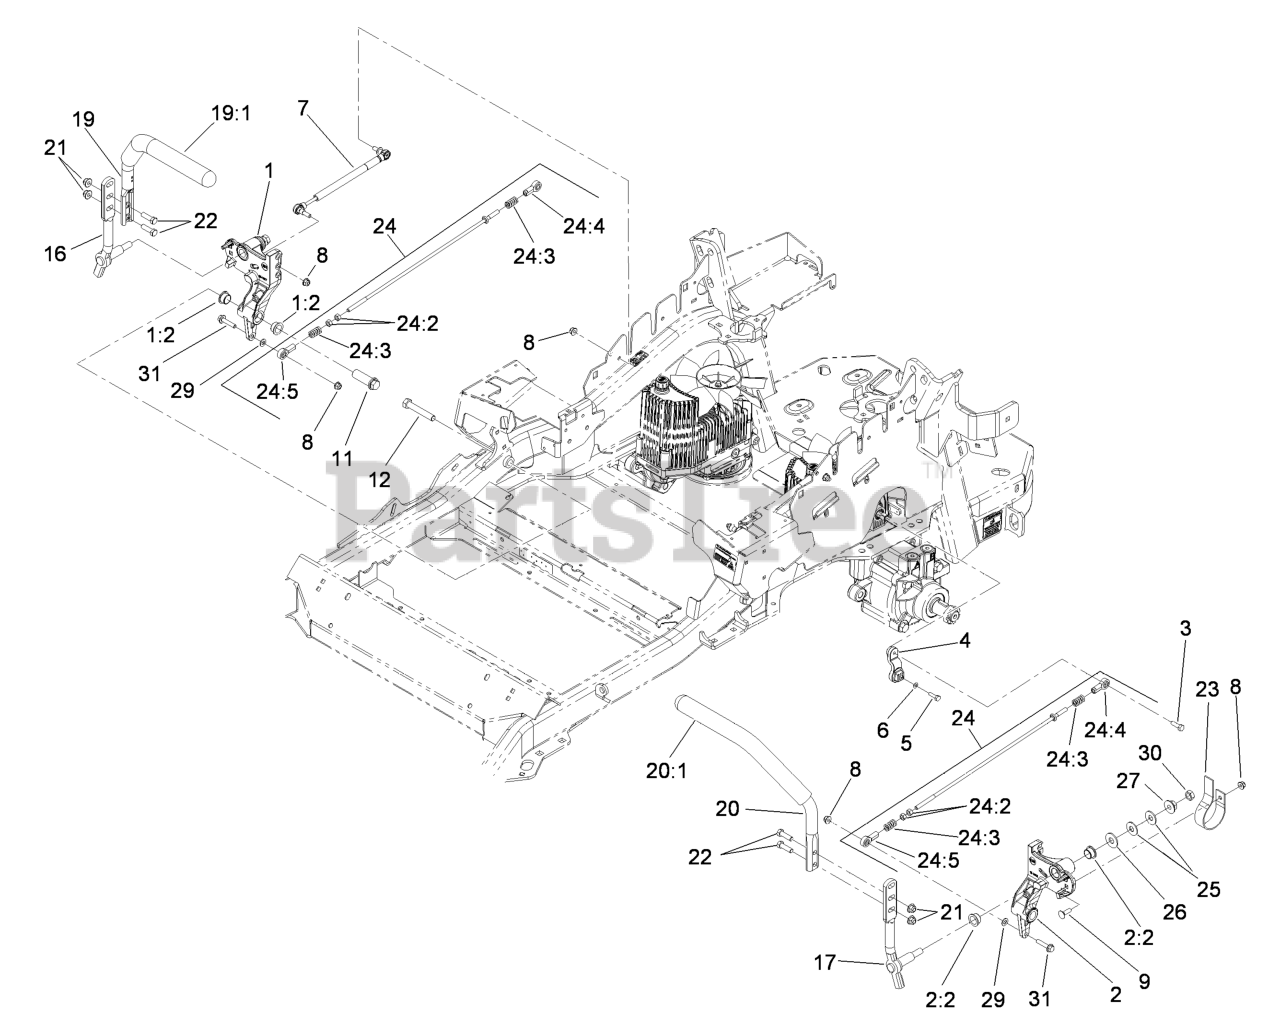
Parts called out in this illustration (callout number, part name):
1	RH MOTION CONTROL AND BUSHING ASM
1:2	BUSHING-FLANGE
2	LH MOTION CONTROL AND BUSHING ASM
2:2	BUSHING-FLANGE
3	SCREW-HH, THREAD LOCKING
4	ARM-CONTROL, PUMP
5	SCREW-HH
6	WASHER-SPRING
7	DAMPER-CONTROL, MOTION
8	NUT-HF, NI
9	BOLT-CARR
11	HUB-THREADED
12	SCREW-HH
16	LEVER-CONTROL MOTION, RH
17	LEVER-CONTROL MOTION, LH
19	RH STEERING HANDLE ASM
19:1	GRIP-LEVER, CONTROL
20	LH STEERING HANDLE ASM
20:1	GRIP-LEVER, CONTROL
21	NUT-HF, NI
22	SCREW-HH
23	SPRING-LEAF
24	PUMP LINKAGE REAR ASM
24:2	NUT-HEX
24:3	SPRING-COMPRESSION
24:4	BALLJOINT-LH
24:5	BALLJOINT-RH
25	WASHER-SPRING
26	WASHER-FLAT
29	WASHER-PLAIN
30	NUT-JAM
31	SCREW-HHF
